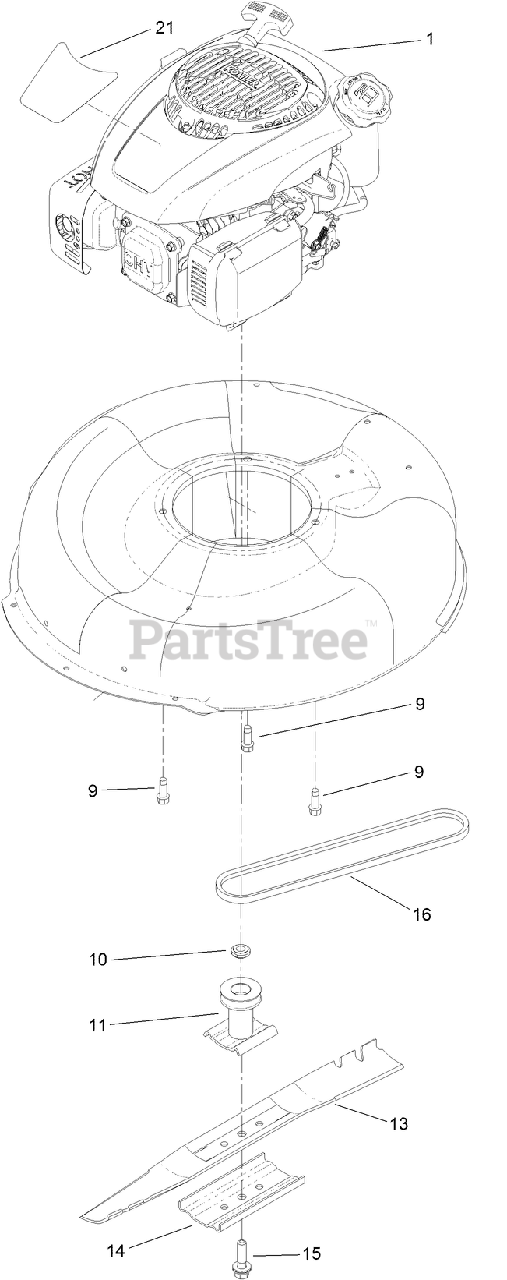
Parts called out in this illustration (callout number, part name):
9	SCREW-TAPTITE
10	SPACER-DRIVER
11	DRIVER-BLADE
14	SUPPORT-BLADE
15	BOLT-BLADE
